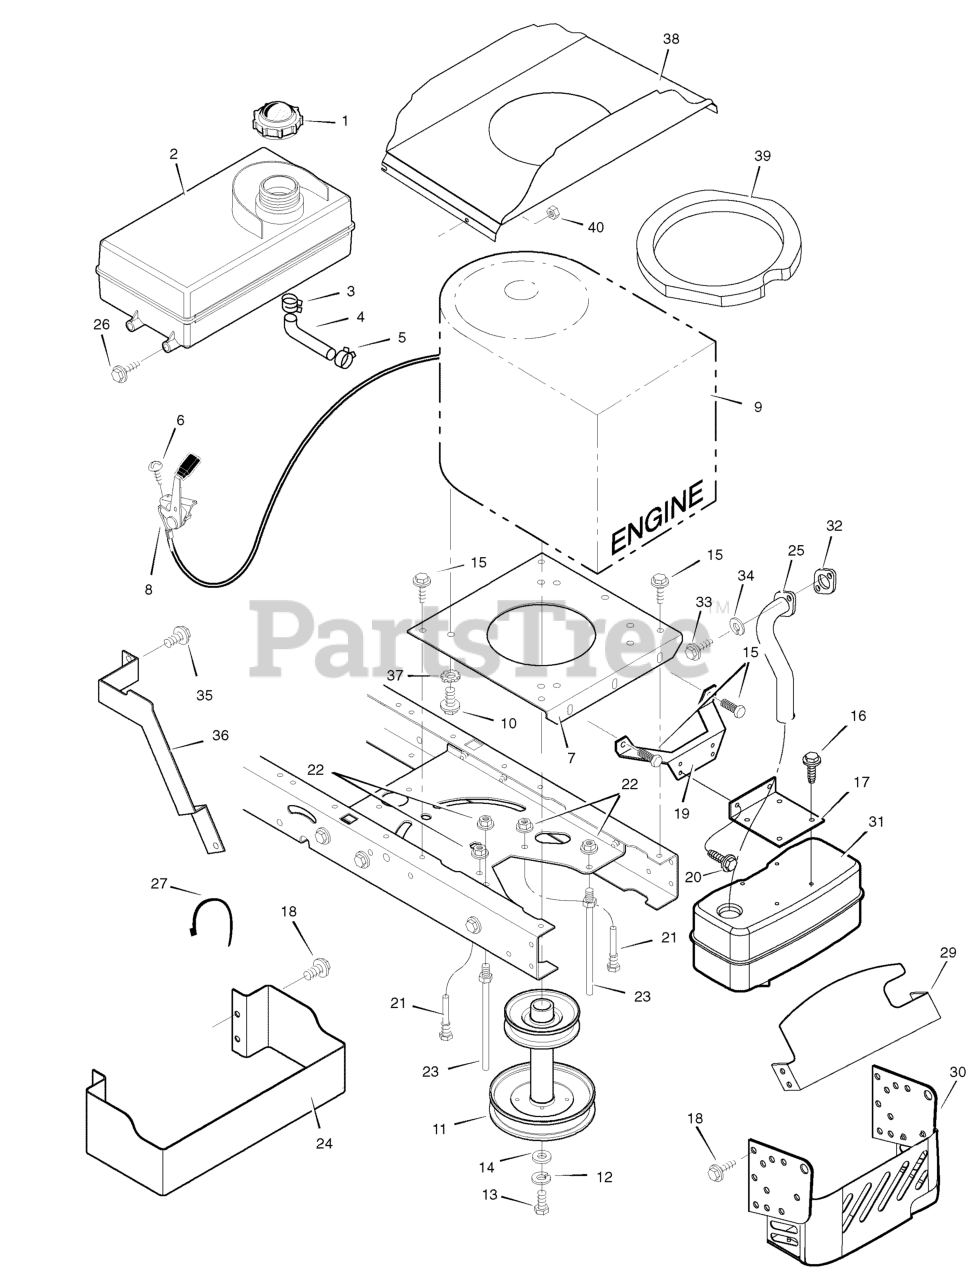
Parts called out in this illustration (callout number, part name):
1	Fuel Cap
2	TANK, Fuel 1.4 Gal.
3	Hose Clamp
4	Fuel Line (Must cut to length)
5	Hose Clamp
7	Plate, Engine
8	Throttle Control
9	Engine, Briggs & Stratton *
10	Bolt, Engine Mount
11	STACK PULLEY ASSEMBLY
12	Lockwasher
13	Bolt, Hex
17	Bracket, Muffler
19	Bracket, Muffler Mount
21	Guide, Belt
22	Nut, Flange
23	Guide, Belt
24	GUARD, Heat Shield
25	Exhaust Tube, Single
27	Tie Strap
29	HEAT SHIELD, Upper
30	Shield, Heat
31	Muffler
32	GASKET, Exhaust
34	Washer
35	Bolt, Washer Hex Head
36	Guard, Exhaust Pipe
37	Washer, Star
40	NUT
